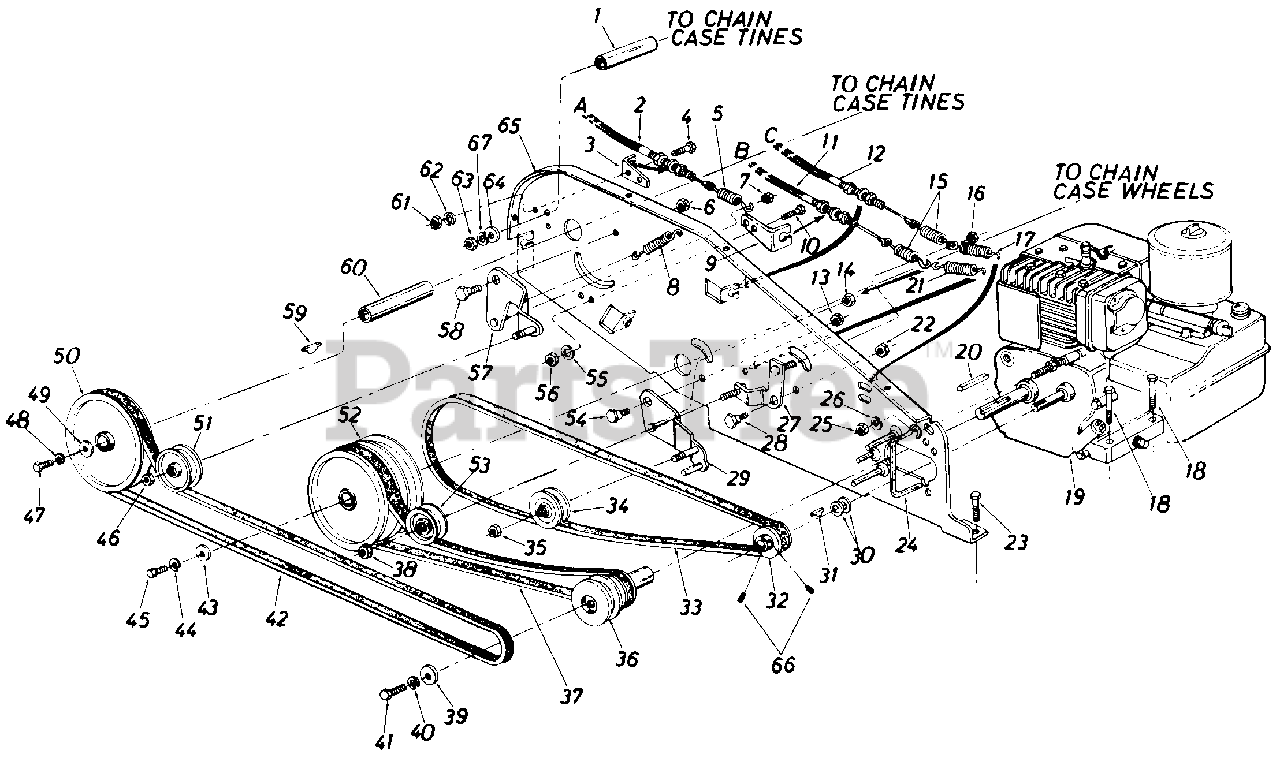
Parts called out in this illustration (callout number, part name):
1	Spacer.375" I.D. x .500" O.D. x 2.00" Lg.
2	Clutch Control Cable
3	Clutch Cable Bracket
4	Hex Bolt 5/16-18 x .75" Lg.*
5	Extension Spring .50" O.D. x 2.50" Lg.
6	Hex Cent. L-Nut 3/8-16 Thd.
7	Hex Cent. L-Nut 1/4" Thd.
8	Extension Spring .50" O.D. x 1.55" Lg.
9	Clutch Cable Bracket
10	Hex Bolt 5/16-18 x .75" Lg.
11	Clutch Control Cable 42" Lg.
12	Clutch Control Cable 41" Lg.
13	Hex Cent. L-Nut 3/8-16 Thd.
14	Hex Cent. L-Nut 1/4-20 Thd.
15	Springs
16	Hex Cent. L-Nut 1/4-20 Thd.
17	Extension Spring .41" O.D. x 2.05" Lg.
18	Hex Bolt 5/16-18 x 1.50" Lg.
20	Sq. Key 3/16 x 1.00" Lg.
21	Extension Spring .50" O.D. x 2.75" Lg.
22	Hex Cent. L-Nut 3/8-16 Thd.
23	Hex Bolt 5/16-18 x .75" Lg.
24	Belt Keeper
25	Hex Nut 1/4-20 Thd.
26	Bell-Wash. .265" I.D. x .75' O.D.
31	#5 Hi-Pro-Key 118" x 5/8" Dia.
32	1/2" V-Pulley 2.25" O.D. x .503" I.D.
33	"V"-Belt 1/2" x 43.0" Lg.
34	"V"-Belt Idler 2.62" O.D.
35	Hex Ins. L-Nut 3/8-24 Thd.
36	1/2" "V"-Pulley Ass'y.
37	"V"-Belt 1/2" x 39.0" Lg.
38	Hex Ins. L-Nut 3/8-24 Thd.
39	Fl-Wash. .344" I.D. x 1.125" O.D.
40	L-Wash. 5/16" I.D.
41	Hex Bolt 5/16-24 x 1.00" Lg.
42	"V"-Belt 1/2" x 54.0" Lg.
43	Fl-Wash. 1/4" I.D. x .93" O.D.
44	L-Wash. 1/4" I.D.
45	Hex Bolt 1/4-28 x .75" Lg.
46	Hex Ins. L-Nut 3/8-24 Thd.
47	Hex Bolt 1/4-28 x .75" Lg.
48	L-Wash. 1/4" I.D.
49	Fl-Wash. 1/4" I.D. x .93" O.D.
50	Fl-Pulley w/Flanges 6.0" O.D.
51	Fl-Idler w/Flanges 3.75" O.D.
52	Double Fl-Pulley 5/8" I.D. x 6.0" O.D.
53	Fl-Idler with Flanges 2.12" O.D.
54	Shld. Bolt .500" Dia. x .170" Lg.
55	L-Wash. 5/16" I.D.*
56	Hex Nut 5/16-18 Thd.
59	#61 Hi-Pro-Key 3116" x 5/8" Dia.
60	Spacer .647" I.D. x 2.75" Lg.
61	Hex Nut 5/16-18 Thd.
62	L-Wash. 5/16" I.D.
63	Hex Nut 5/16-18 Thd.
64	Fl-Wash. .406" I.D. x .750" O.D.
65	Side Plate Ass'y.
66	Set Scr. 1/4-28 x .25" Lg.
67	L-Wash. 5/16" I.D.
